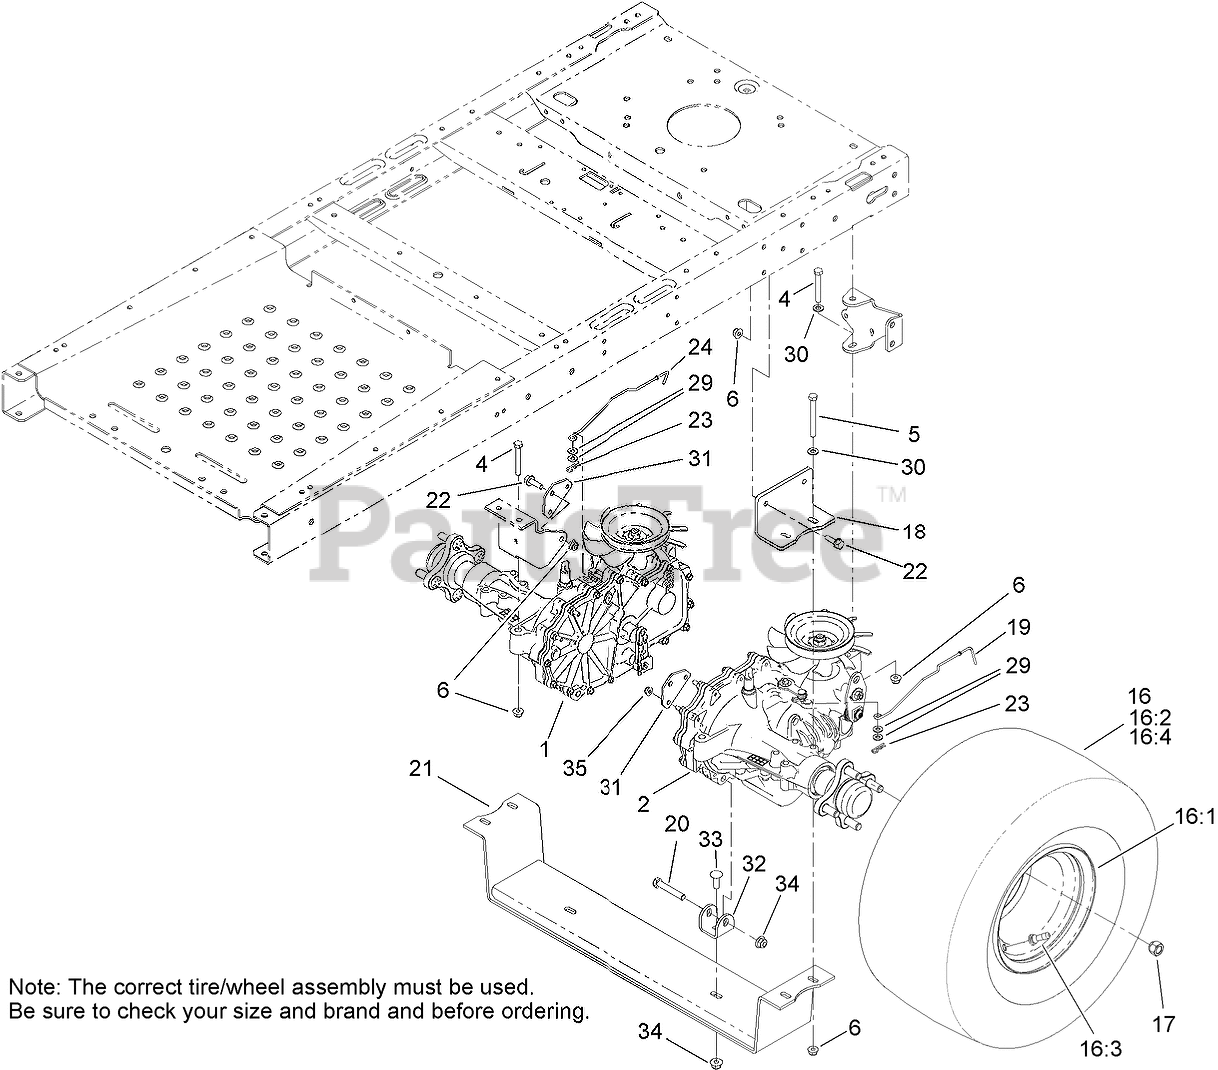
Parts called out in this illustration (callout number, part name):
1	RH HYDRO TRANSAXLE ASM
2	LH HYDRO TRANSAXLE ASM
4	SCREW-HH
5	SCREW-HH
6	NUT-HF, NI
16	Wheel and Tire ASM (Kenda)
16	Wheel and Tire ASM (K-500)
16	Wheel and Tire ASM (Premium)
16:2	TIRE-4 PLY
16:3	STEM-VALVE
16:4	TUBE-INNER
17	NUT-LUG
18	MOUNT-HYDRO
19	ROD-BYPASS, LH
20	SCREW-HH
21	MOUNT-HYDRO
22	SCREW-HHF
23	PIN-COTTER
24	ROD-BYPASS, RH
29	WASHER-FLAT
30	WASHER-PLAIN
31	PLATE-HYDRO MOUNT
32	TAB-HYDRO
33	SCREW-CARR
34	NUT-HF, NI
35	NUT-HF
